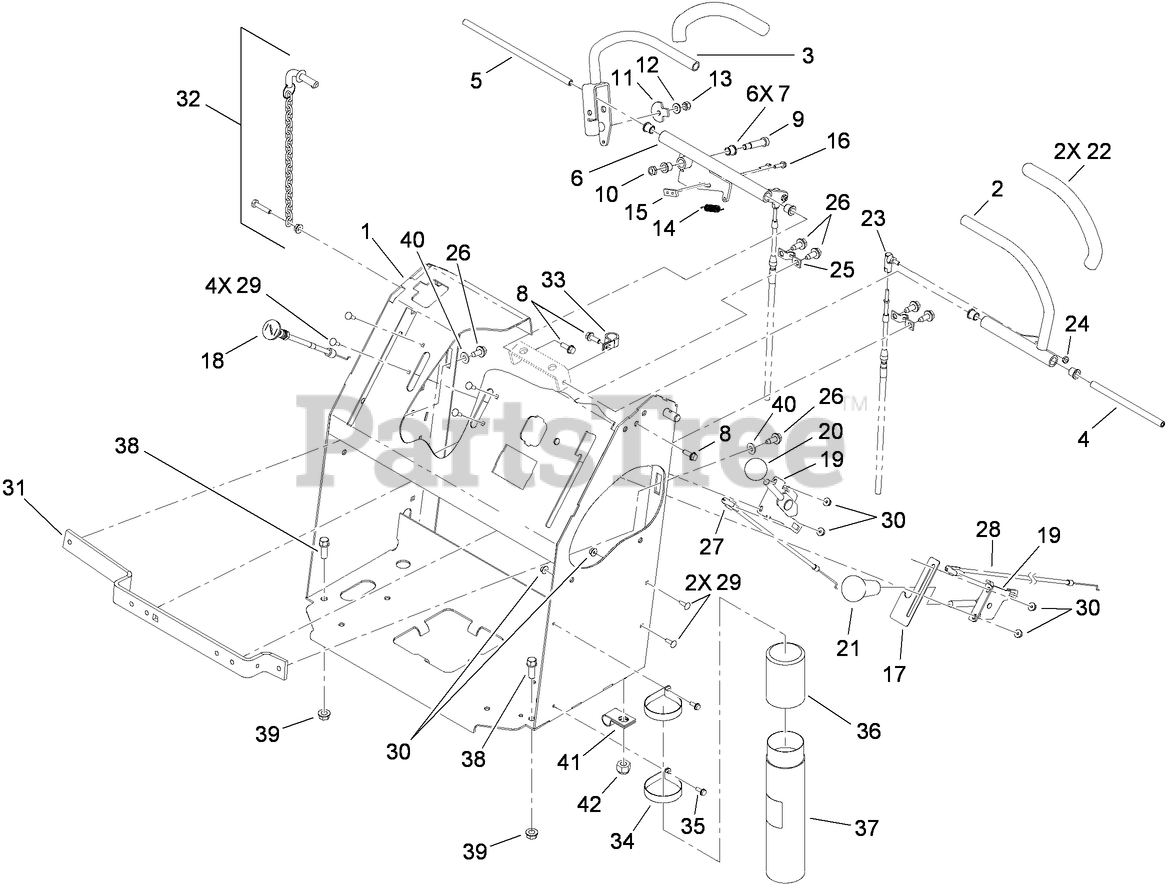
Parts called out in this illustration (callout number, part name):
1	CONTROL TOWER ASM
2	LH LEVER ASM
3	RH LEVER ASM
4	SHAFT-PIVOT
5	SHAFT-PIVOT, MOTION CONTROL
6	MOTION CONTROL ASM
7	BEARING
8	SCREW-HHF
9	SCREW-HSH
10	NUT-LOCK, NI
11	CAM-LEVER
12	WASHER-FLAT
13	NUT-LOCK, NI
14	SPRING-EXTENSION
15	PLATE-TAPPED
16	SCREW-HWH
17	PLATE-CONTROL, LIMITER
18	Control-Choke, Push / Pull
19	LEVER-CONTROL
20	KNOB-BALL
21	KNOB-GRIP, SOFT
22	GRIP-LEVER
23	JOINT-BALL
24	NUT-LOCK, NI
25	CLAMP-CABLE
26	SCREW-HWHTF
27	CABLE-CONTROL
28	CABLE-SPEED
29	BOLT-CARR
30	NUT-HF
31	BAR-CABLE
32	HOC PIN ASM
33	CLAMP-CABLE
34	CLAMP-R
35	SCREW-TAPTITE
36	CAP-HOUSING
37	TUBE-MANUAL
38	SCREW-HWH
39	NUT-HHF, WHIZ
40	WASHER-PLAIN
41	R-CLAMP
42	NUT-LOCK, NI
